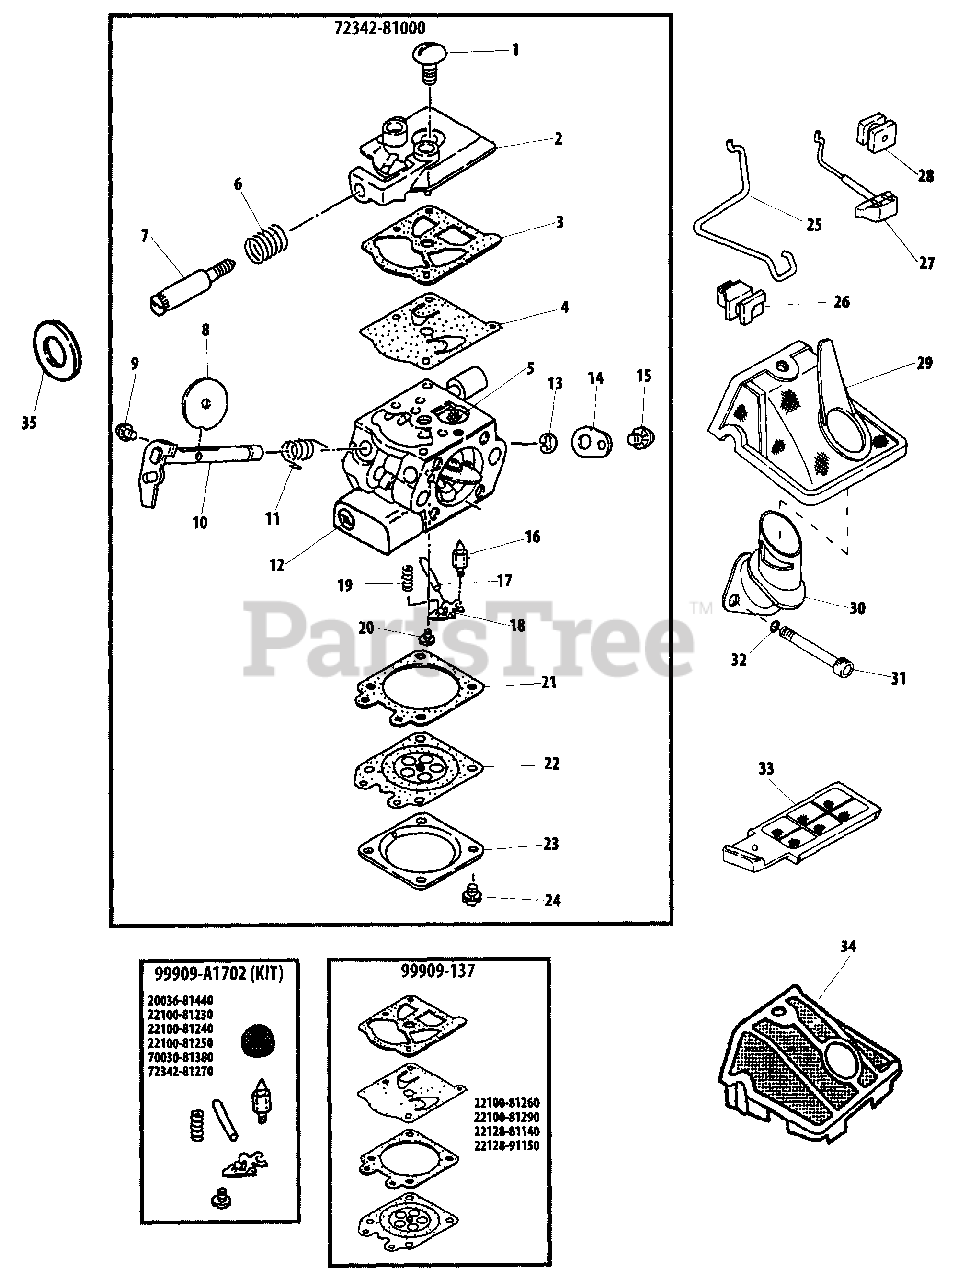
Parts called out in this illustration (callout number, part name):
1	SCREW, PUMP COVER
2	COVER, PUMP
3	GASKET, PUMP
4	DIAPHRAGM, PUMP
5	STRAINER
6	SPRING
7	SCREW, IDLE ADJUST
8	VALVE, THROTTLE
9	SCREW
10	SHAFT, THROTTLE
11	SPRING, RETURN
12	CAP, LIMITER
13	RING, RETAINING
14	TRIGGER, THROTTLE
15	SCREW
16	VALVE, INLET NEEDLE
17	PIN, METERING LEVER
18	LEVER, METERING
19	SPRING, METERING LEVER
20	SCREW, METERING LEVER PIN
21	GASKET, METERING
22	DIAPHRAGM, METERING
23	COVER, DIAPHRAGM
24	SCREW
25	ROD, THROTTLE
26	GROMMET
27	ROD, CHOKE
28	GROMMET
29	FILTER, AIR
30	ELBOW
31	SCREW - 5X40
32	WASHER - 5
33	PRE-FILTER
34	FILTER, AIR - FLOCKED
35	SEAL
72342-81000	CARBURETOR
99909-137	DIAPHRAGM/GASKET KIT
99909-A1702	REPAIR KIT
